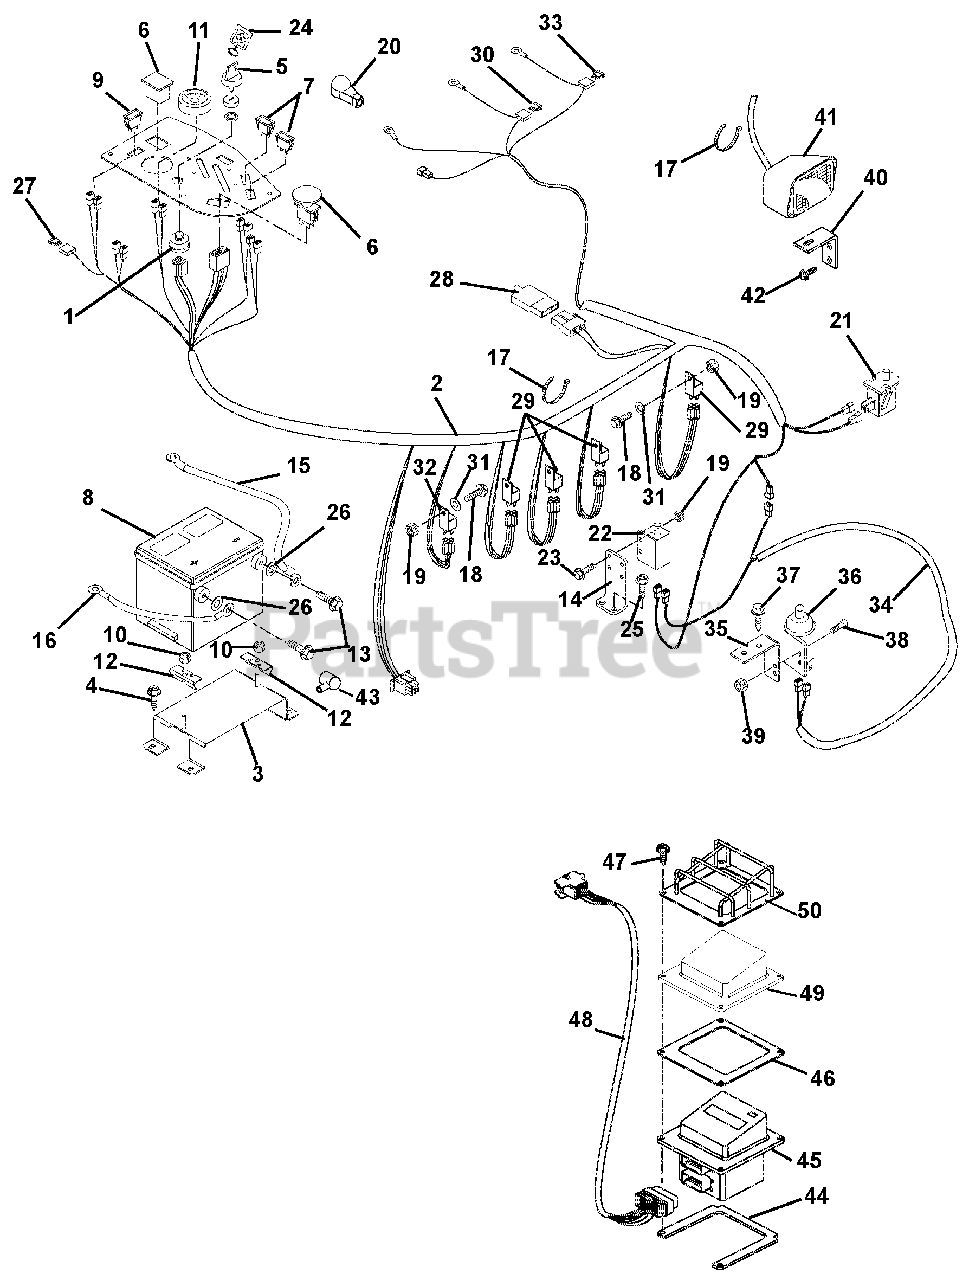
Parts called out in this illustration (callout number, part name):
1	Switch, Ignition (Diesel)
2	Harness, Wiring (Diesel)
3	Weldment, Battery Support
4	Screw-Tapping .38-16 x .75 Hex Washer Head
5	Key-with Cap
6	Plug 01545600 1Switch-Clutch With Retainer Ring
7	Light-Indicator Kit
8	Battery with Tube
9	Switch, Light
10	Nut-Locking-Top-Flange .31-18
11	Gauge, Temperature
12	Bracket, Battery Hold-Down
13	Bolt-Hex .25-20 x .75 Grade 5
14	Mount, Safety Switch
15	Positive Cable
16	Cable, Negative Battery
17	Cable Tie
18	Screw-Machine 10-24 x .75 Hex Washer Head
19	Nut-Locking-Nylon 10-24 With Insert
20	Eyelet Terminal Boot
21	Switch, Snap Mounting (N.O.) (Included with Seat)
22	Switch-Single Pole
23	Screw-Machine 10-24 x .75 Hex Washer Head
24	Key Chain
25	Screw-Tapping .25-20 x .50 Hex Washer Head
26	Washer-Flat-Steel .406 x 1.00 x ..083
27	Fuse, 15 Amp
28	Diode, Connector Shell
29	Relay (Included with Harness)
30	Fuse, 30 Amp (Included with Harness)
31	Washer-Flat-Steel .25 x .562 x .049
33	Fuse, 50 AMP (Maxi Fuse) (Included with Harness)
34	Harness, Wire Adapter CE
35	Mount- Switch
36	Switch-Single Pole (N.O.) with Cover
37	Screw-Tapping .31-18 x .50 Hex Washer Head
38	Screw-Machine 10-24 x .75 Hex Washer Head
39	Nut-Locking-Nylon 10-24 with Insert
40	Bracket, Headlight Mounting
41	Headlight
42	Screw-Tapping .38-16 x .50 Hex Washer Head
43	Boot, Eyelet Terminal
44	Spacer, Enclosure Mounting (Bottom)
45	Assembly, Eye-Q
46	Gasket, Eye-Q
47	Screw, Machine 10-24 x 1.0 Slotted Pan Black
48	Harness Jumper (Eye-Q)
49	Guard, Element
50	Guard, Vinyl Eye-Q
